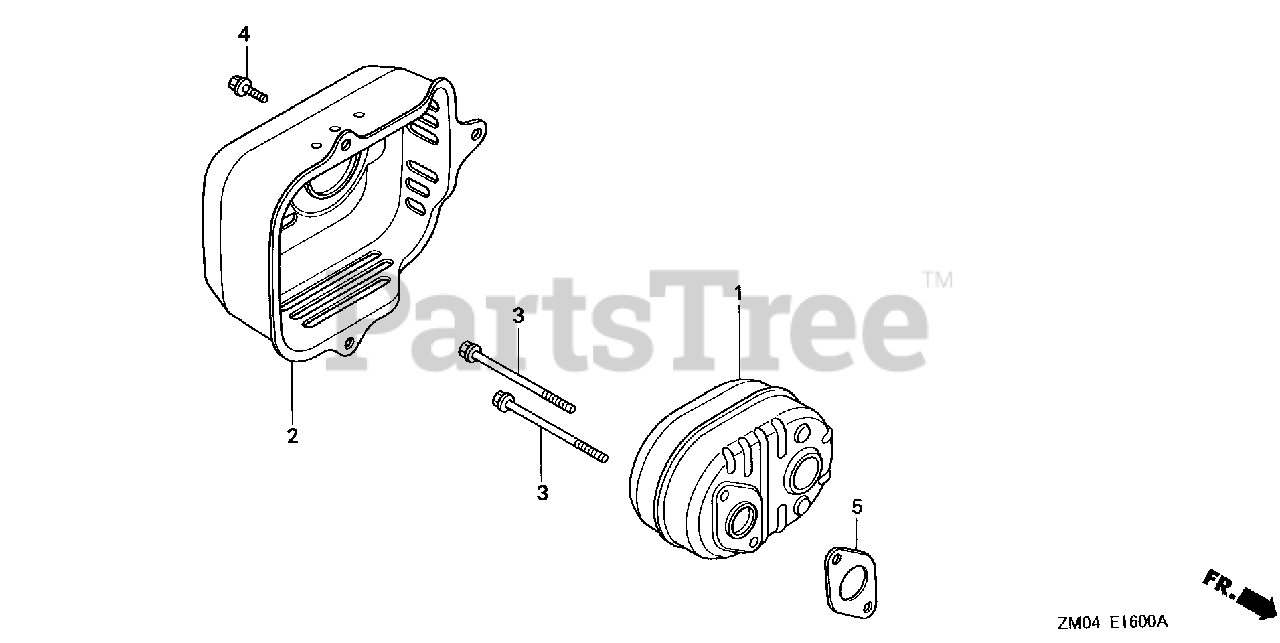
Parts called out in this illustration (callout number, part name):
1	MUFFLER
2	PROTECTOR, MUFFLER
3	BOLT, FLANGE (6X79) (CT200)
4	BOLT, FLANGE (6X12) (CT200)
5	GASKET, MUFFLER
